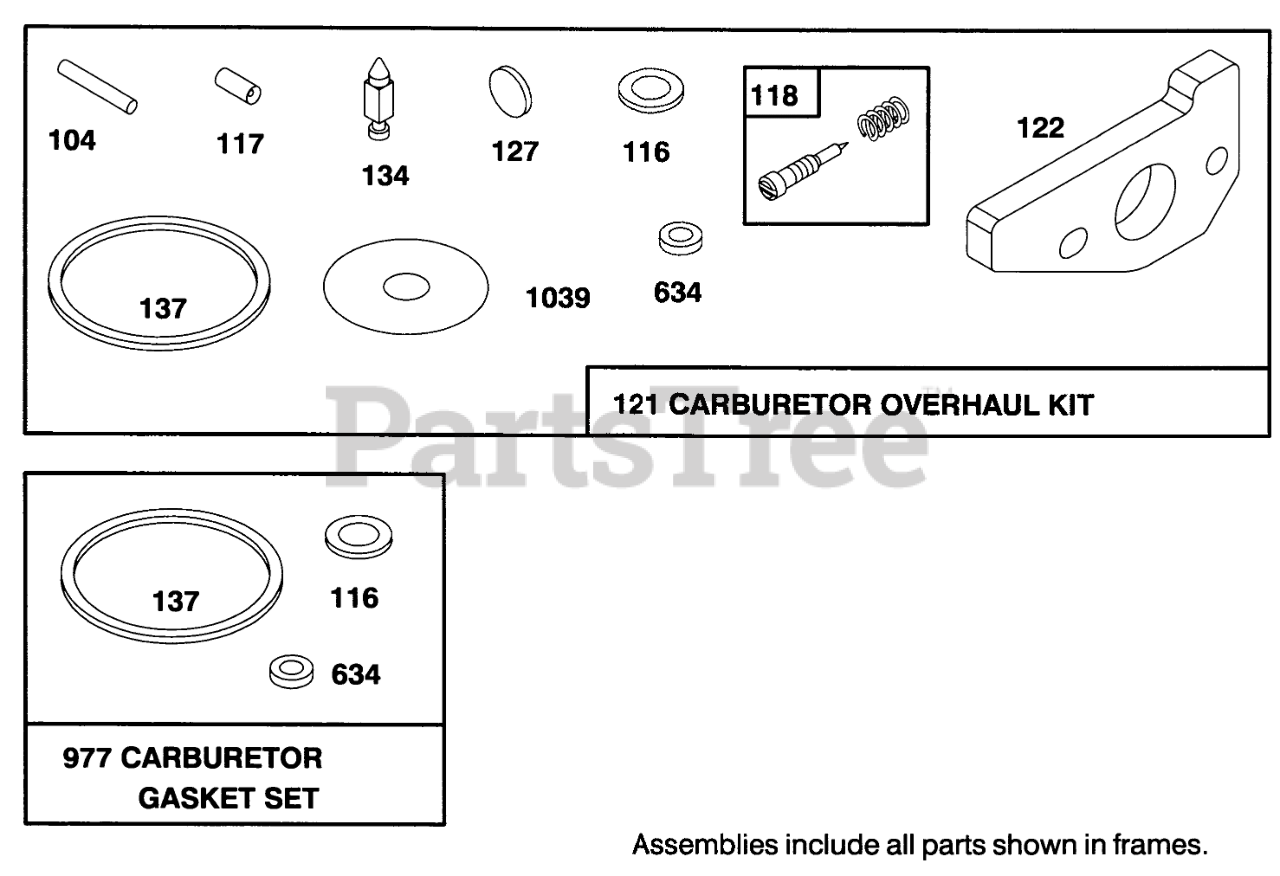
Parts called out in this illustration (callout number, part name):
104	FLOAT HINGE PIN
116	SEALING GASKET
118	VALVE KIT - NEEDLE
121	CARBURATOR OVERHAUL KIT
122	ADAPTER ASSEMBLY
134	Valve-Float (Includes Seat)
137	FLOAT BOWL GASKET
358	GASKET SET
634	SEAL WASHER
977	CARBURATOR GASKET SET
1039	FLOAT LIMITER
